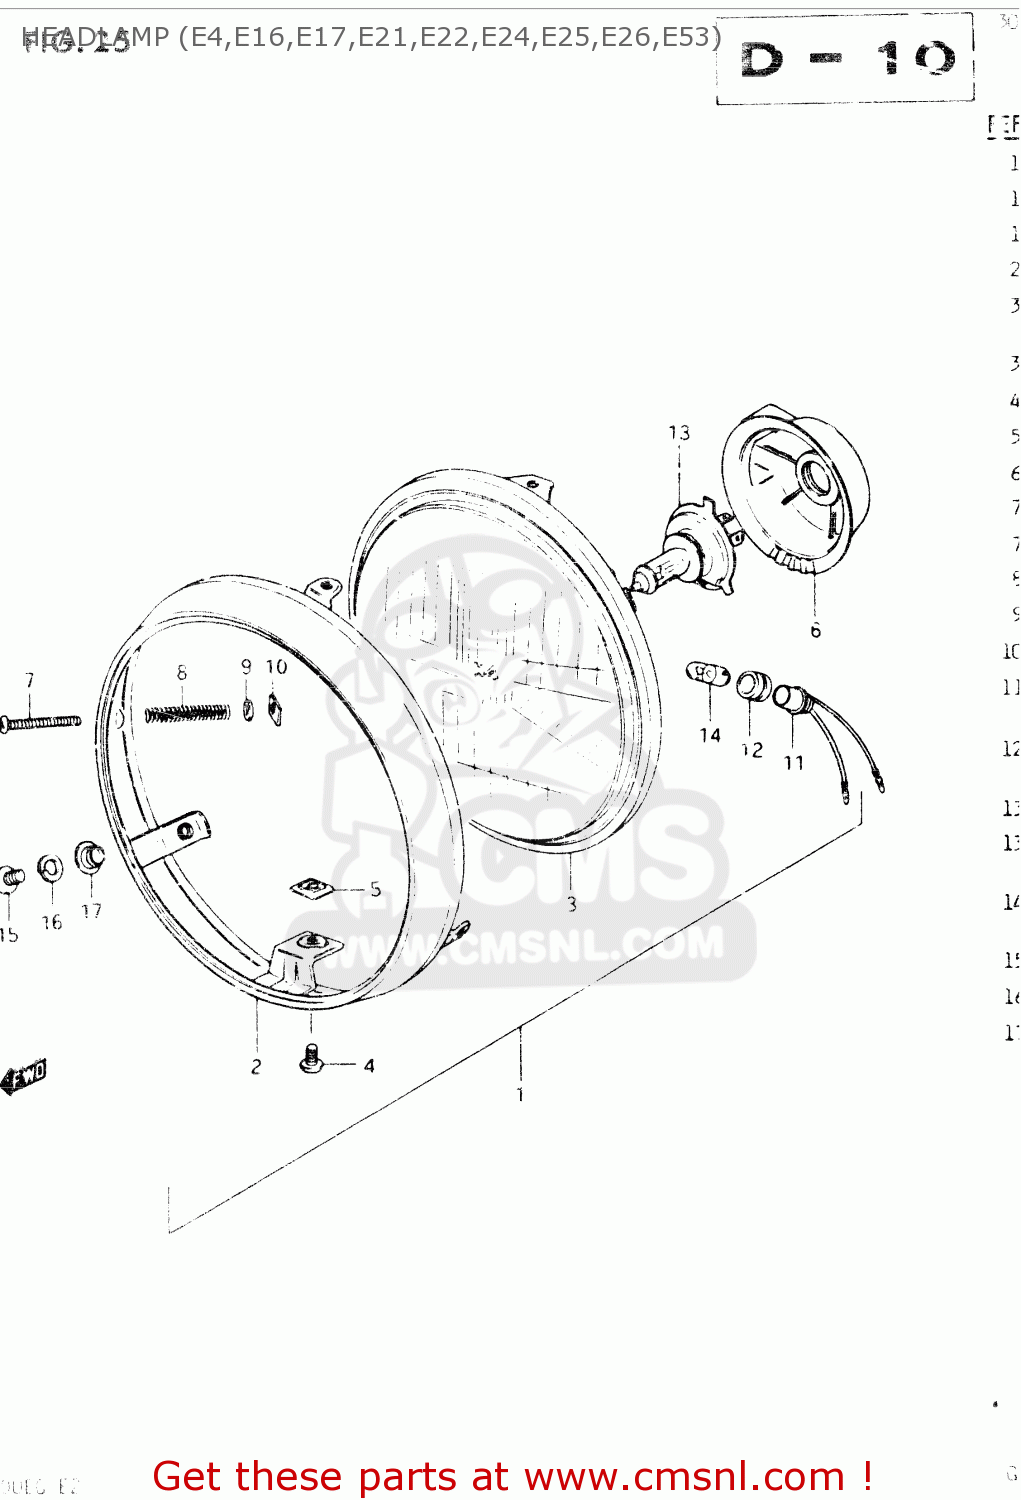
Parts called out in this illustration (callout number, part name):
1	HEADLAMP ASSY
2	RIM
3	LAMP UNIT
4	SCREW
5	NUT,ADJUSTING
6	COVER,SOCKET
7	SCREW
8	SPRING
9	WASHER
10	NUT,HEADLAMP ADJUSTER
11	SOCKET
12	JOINT,RUBBER
13	BULB(12V60/55W,H4)
14	BULB(12V4W)
15	SCREW
16	WASHER,LOCK
17	WASHER
